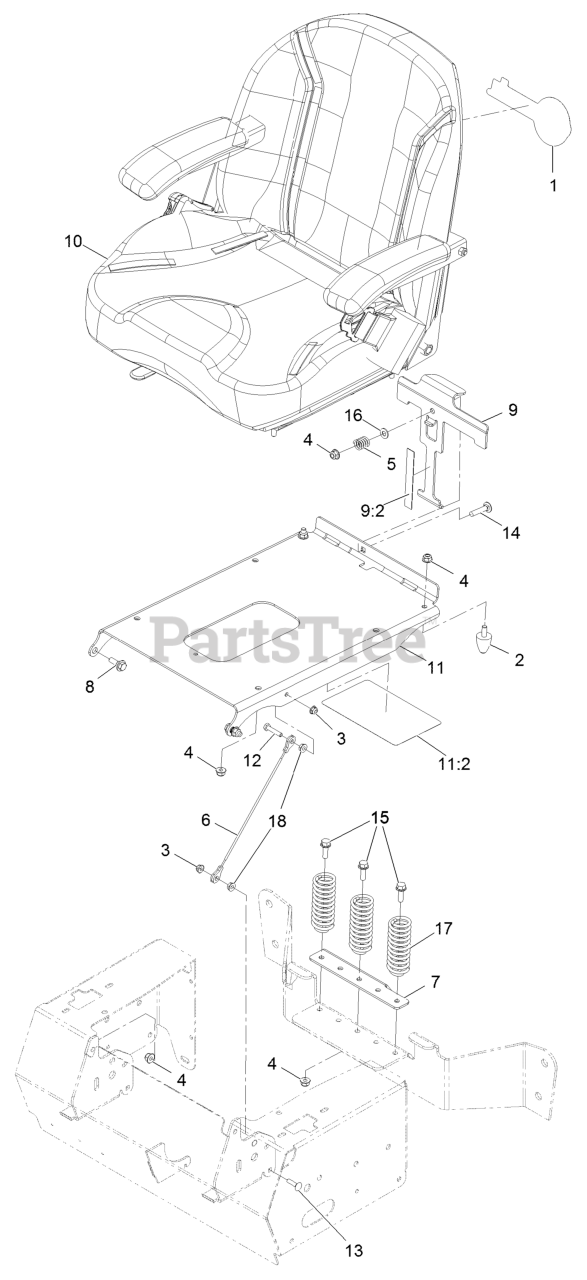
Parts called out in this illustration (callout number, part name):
1	DECAL, EXMARK LOGO
2	BUMPER-SEAT
4	NUT-HF, NI
5	SPRING-COMPRESSION
6	CABLE-STOP, SEAT
7	CATCH,SEAT LATCH
8	SCREW-SHOULDER
9	ASM-SEAT LATCH
9:2	STRIP-POLY WEAR
10	ASM-SEAT,PIONEER
11	PLATE, SEAT W/DECALS
11:2	DECAL-SERVICE AID
12	SCREW-HH
13	SCREW-CARR
14	BOLT-CARR
15	SCREW-HHF
16	WASHER-PLAIN
17	SPRING-COMPRESSION
